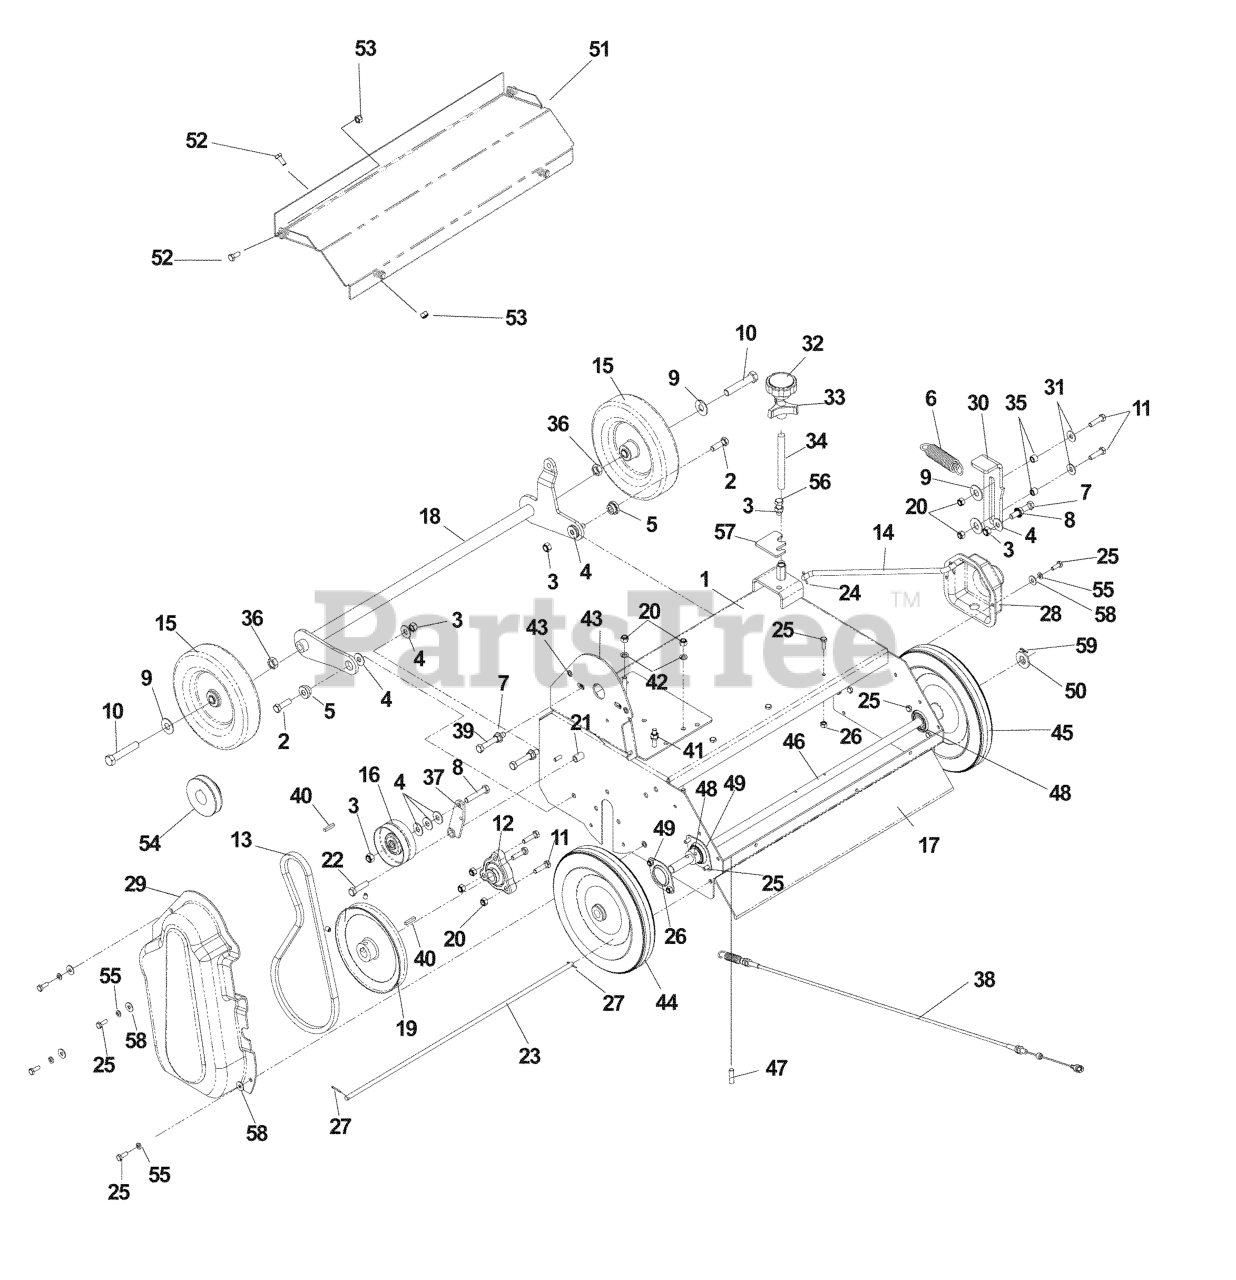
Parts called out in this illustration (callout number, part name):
1	BODY ASSEMBLY
2	HCS 3/8C X 1 1/4 GR5
3	NUT 3/8-16 NYLOC
4	WASHER 3/8 FLAT
5	BUSHING RAKE
7	NUT 3/8C WHIZ
8	HCS 3/8C X 2
9	WASHER 1/2 FLAT
10	HCS 1/2C X 2 3/4
11	HCS 5/16C X 1 1/4
12	BEARING, FLANGED
13	BELT, DRIVE RAKE/SLICER DFS
15	WHEEL 8 X 1 3/4 RAKE
16	PULLEY, IDLER RAKE & ZTR
18	FRONT AXLE
19	PULLEY W/SET SCREW
20	NUT 5/16 NYLOC
21	BEARING, ONLITE RAKE/DT
22	HCS 3/8C X 1 1/2
24	RP_COTTER PIN 1/8 X 3/4
25	HCS 1/4C X 3/4 HCS
26	NUT.1/4-20.HEX.NYLOC.ZD
27	RP_COTTER PIN 1/8 X 3/4
28	SHAFT GUARD
29	BELT GUARD
31	WASHER 5/16 FLAT
32	KNOB, BLACK THERMO PLASTIC
33	KNOB, THREE PRONG
34	THREADED ROD
36	NUT 1/2 HEX JAM
37	IDLER ARM - ORANGE
38	CABLE POWER RAKE
39	HCS 3/8C X 2 1/2
40	KEY
41	HCS 5/16C X 1 3/4
42	WASHER.LOCK.HVY.HLCL.SPR.5/16
43	BACKING PLATE ORANGE
44	WHEEL 10 X 1 3/4
45	WHEEL 10 X 1 3/4
46	AXLE, REAR
47	ROLL PIN 1/4 X 1 1/8
48	BEARING - 5/8" W/COLLAR
49	FLANGE
50	WASHER
51	REAR COVER ORANGE
52	HCS 1/4C X 5/8
53	NUT.1/4-20.HEX.NYLOC.ZD
54	ENGINE PULLEY W/SET SCW
55	LOCKWASHER 1/4"
56	HCS 3/8-16X1.GRD.5.ZD
57	DEPTH SHIM
58	WASHER 1/4 FLAT
59	COTTER PIN
60	KNURLED INSERT
